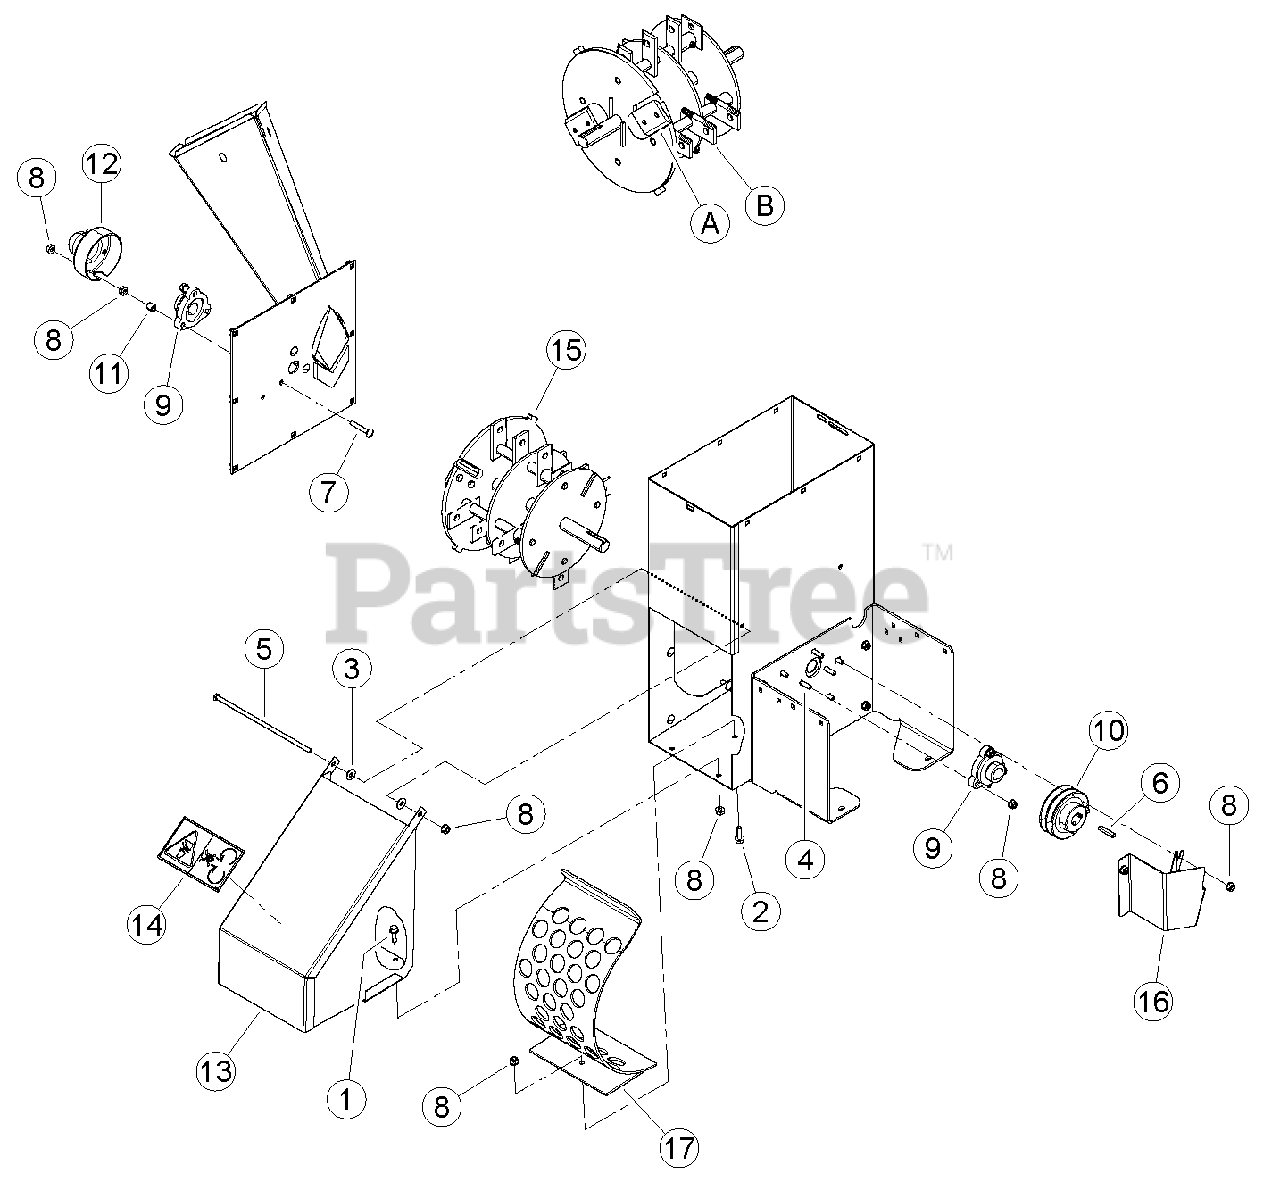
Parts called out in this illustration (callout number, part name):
1	BOLT, 5/16 X 3/4 FLANGE NC
2	BOLT, 5/16 X 1 FLANGE NC
3	WASHER, 5/16 FLAT ZP
4	BOLT, 5/16 X 1-1/4 CRG GR5 ZP
5	BOLT, 5/16 X 10 HEX GR5 NC ZP
6	KEY, 1/4 SQUARE X 1-1/2 LONG PLAIN
7	BOLT, 5/16 X 2 CRG GR5 NC ZP
8	NUT, 5/16-18 NYLOCK-FLANGE
9	BEARING, 1" FLUSHMOUNT CAST W/ COLLAR
10	PULLEY, 4 X 1 2A GROOVE
11	SPACER, .54 OD X .50" LG
12	CAP, ROTOR SHAFT END CAP
13	ASSEMBLY, WIDE EUROPEAN DISCHARGE
13	ASSEMBLY, NARROW EUROPEAN DISCHARGE (SC3206XE ONLY)
14	DECAL, BLADE DANGER ISO
15	ASSEMBLY, BALANCED ROTOR
16	SHIELD, LOWER
17	WELDMENT, WIDE COARSE TAPERED
A	KIT, TOOL STEEL BLADE
B	KIT, 3" WIDE SHREDDER KNIVES
